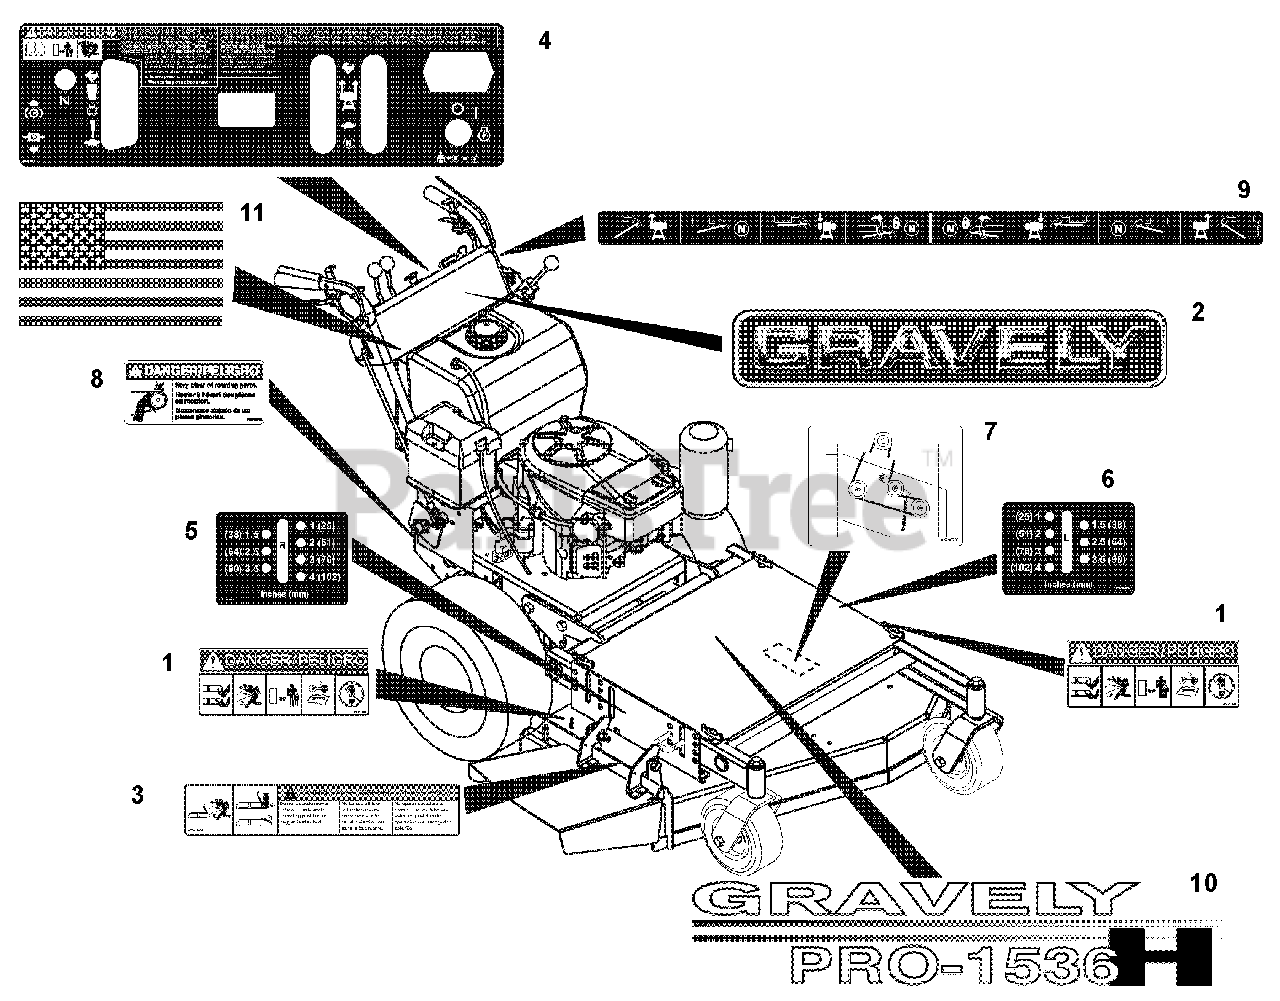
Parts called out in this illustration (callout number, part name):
1	Decal, Mower Pan Head Danger
2	Decal- 15" Gravely Logo
3	Decal, Warning
4	Decal, Control HR15 (105, 106, 113, 312)
5	Decal, Height of Cut-Fixed- Right Hand
6	Decal, Height of Cut-Fixed- Left Hand
7	Decal, Belt Diagram-2 Spindle (105, 120, 312, 314)
8	Decal, Danger-Belt Rotating
9	Decal, Steer Levers (Hydro)
10	Decal, Pro 1536H (105, 120, 312, 314)
11	Decal, American Flag
